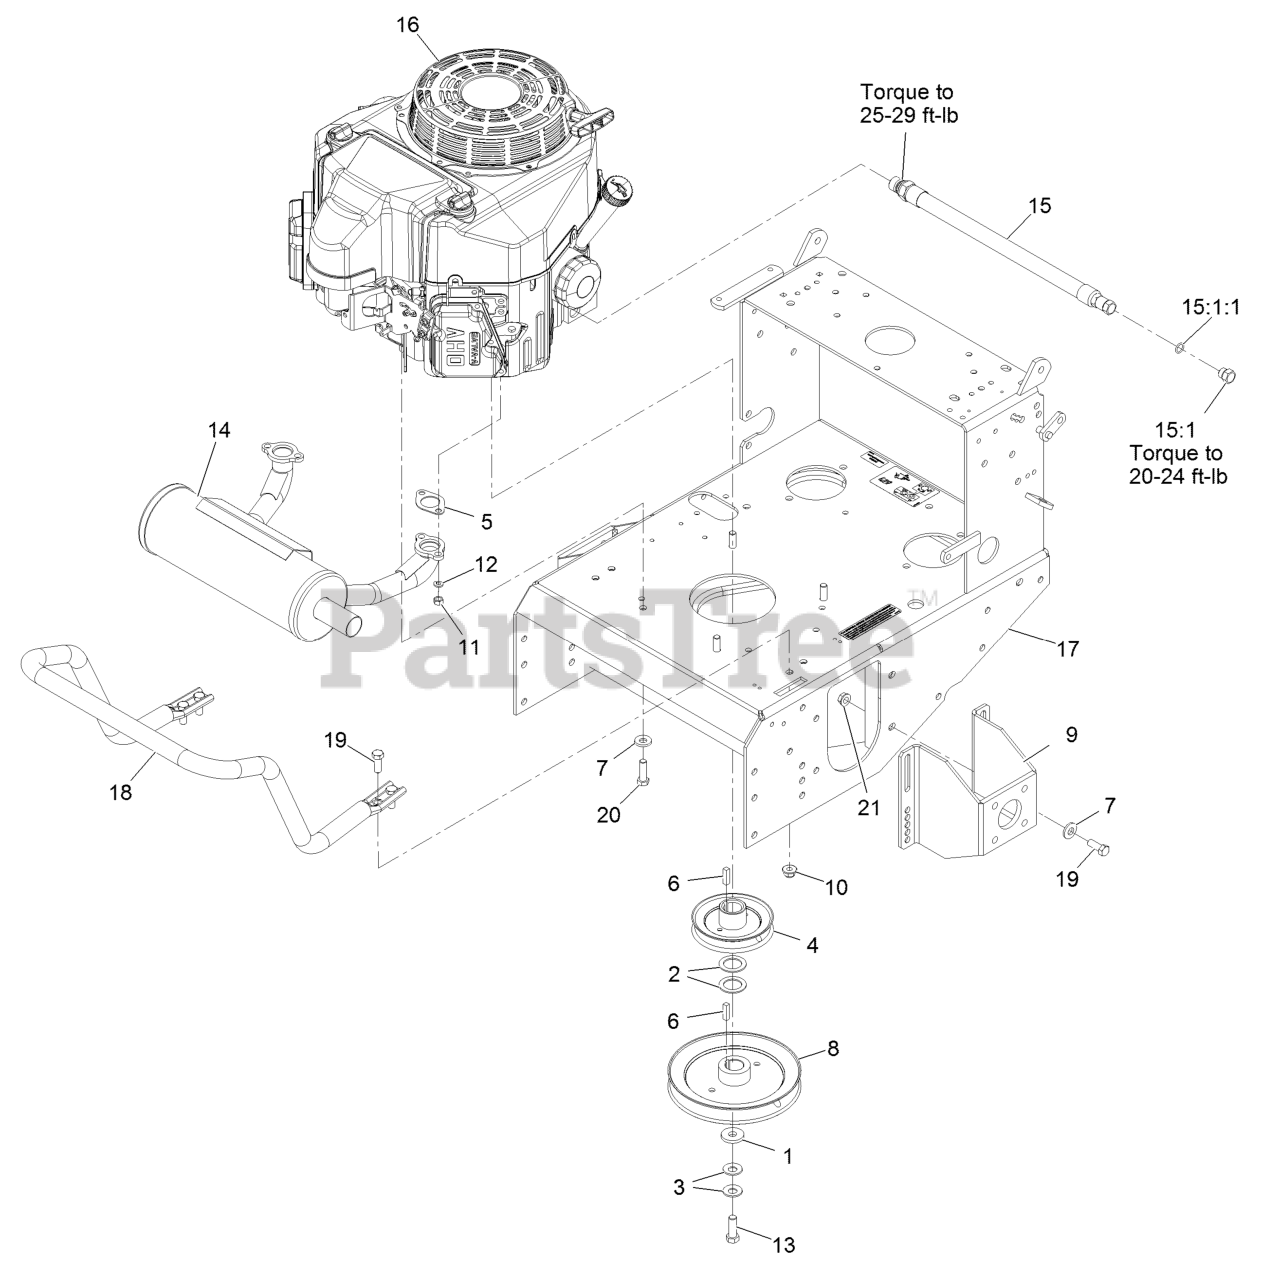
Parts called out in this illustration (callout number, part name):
2	WASHER-SPACER
3	WASHER-SPRING
5	GASKET-EXHAUST
7	WASHER-BELLEVILLE
9	MOUNT-MOTOR
10	NUT-HF, NI
12	WASHER-LOCK
13	SCREW-HH
14	MUFFLER-HORIZONTAL
15	ASM, ENGINE OIL DRAIN HOS
15:1	PLUG-HH
15:1:1	O-RING
16	Engine-Kawasaki
17	ASM, VH ENGINE DECK W/DEC
18	GUARD-MUFFLER
19	SCREW-HH
20	SCREW-HH
21	NUT-HHF, WHIZ
